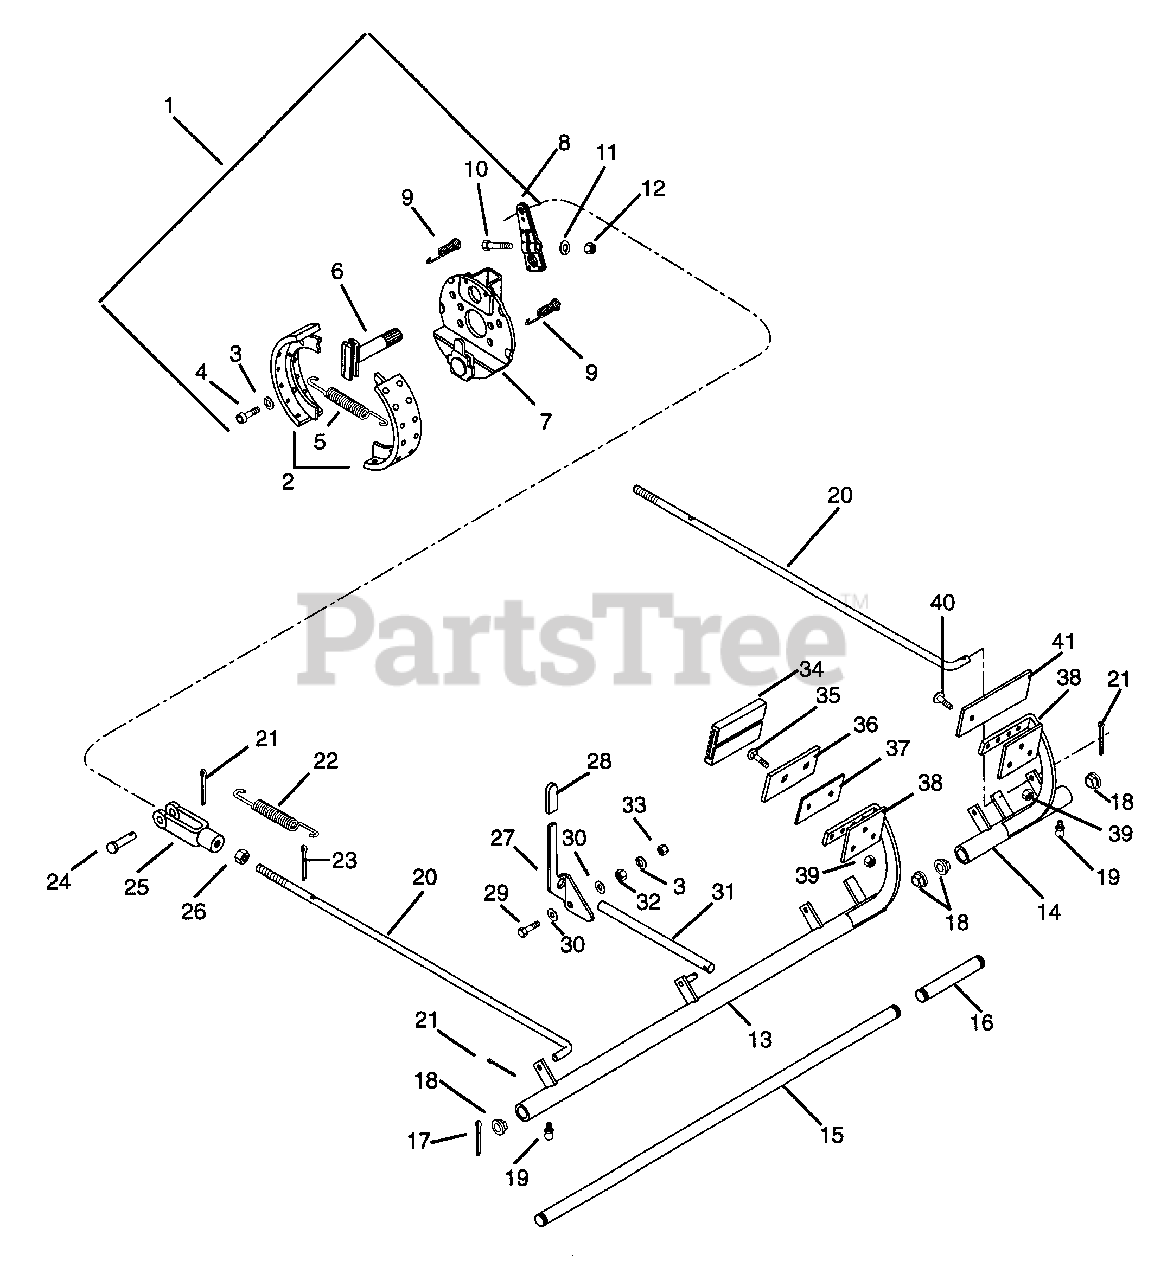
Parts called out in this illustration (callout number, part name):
1	Brake, 7 x 1.75 Mechanical
2	Kit,Brake Shoe
3	Washer-Lock .375 x .094
4	Screw-Cap .38-16 x 1.25
5	Spring,Shoe Return
6	Cam,Brake
7	Plate,Back
8	Arm,Cam Lever
9	Spring,Shoe Ret Box
10	Bolt-Hex .31-24 x 1.75
11	Washer-Lock .313 x .078
12	Nut-Hex .312-24 Grade 2
13	Weldment,Brake Pedal Right Hand
14	Weldment,Brake Pedal Left Hand
15	Shaft,Brake Pivot Long
16	Shaft,Brake Pivot Short
17	Pin-Cotter .12 x 1.25
18	Bushing-Flange .630 x 1.000 x .625
19	Fitting-Lube .25-28 x .256
20	Rod,Brake
21	Pin-Cotter .09 x .75
22	Spring-Tension .091 x .500 x 5.50
23	Pin-Cotter .12 x .75
24	Pin-Clevis .375 x .948
25	Clevis, .38-24 Adjustable
26	Nut-Jam .375-24
27	Arm,Parking Brake Lock
28	Tip-Brake Lock Lever
29	Bolt-Hex .38-16 x 1.38
30	Washer-Flat-Nylon .375 x .75 x .060
31	Rod,Brake Lock
32	Nut-Hex .375-16 Grade 2
33	Nut-Hex .50-20
34	Pad,Pedal
35	Bolt-Round Head Square Neck .25-20 x 1.25
36	Pedal,Brake
37	Plate,Brake
38	Plate,Brake Lock Backing
39	Nut-Locking-Nylon .250-20 Grade 2
40	Screw-Machine .25-20 x 1.00
41	Arm,Brake Lock
